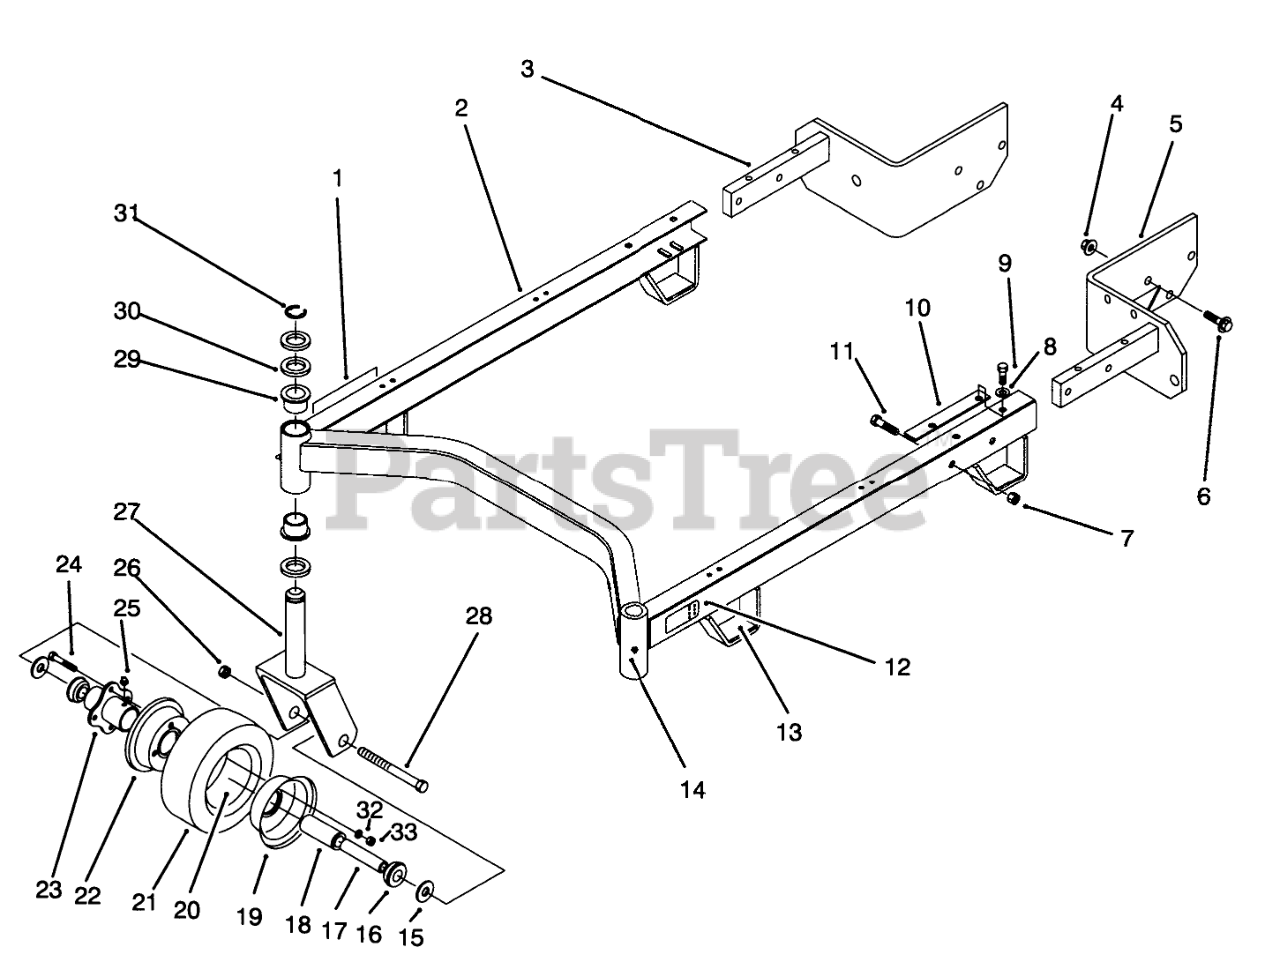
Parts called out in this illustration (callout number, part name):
1	DECAL-HOC, RH
2	Suspension Frame W.A.
3	Bracket RH
4	NUT-HF
5	Bracket-LH
6	SCREW-HHF
7	NUT-LOCK, CONE
8	WASHER-FLAT
9	SCREW W/PATCH
10	SHIM-CARRIER
11	SCREW-HH
12	DECAL-HOC, LH
13	CUSHION-RUBBER
14	FITTING-GREASE
15	WASHER-FLAT
16	BEARING-OUTSIDE
17	SPANNER-TIRE
18	BEARING-ROLLER
19	MALE WHEEL HALF
20	TUBE-INNER (W/VALVE)
22	FEMALE WHEEL HALF
23	HUB-CENTER
24	WHEEL BOLT
25	FITTING-GREASE
26	NUT-HEX
27	Castor Fork
28	SCREW-HH
29	Bushing
30	WASHER-THRUST
31	RING-RETAINING
32	WASHER-LOCK
33	NUT-HEX
